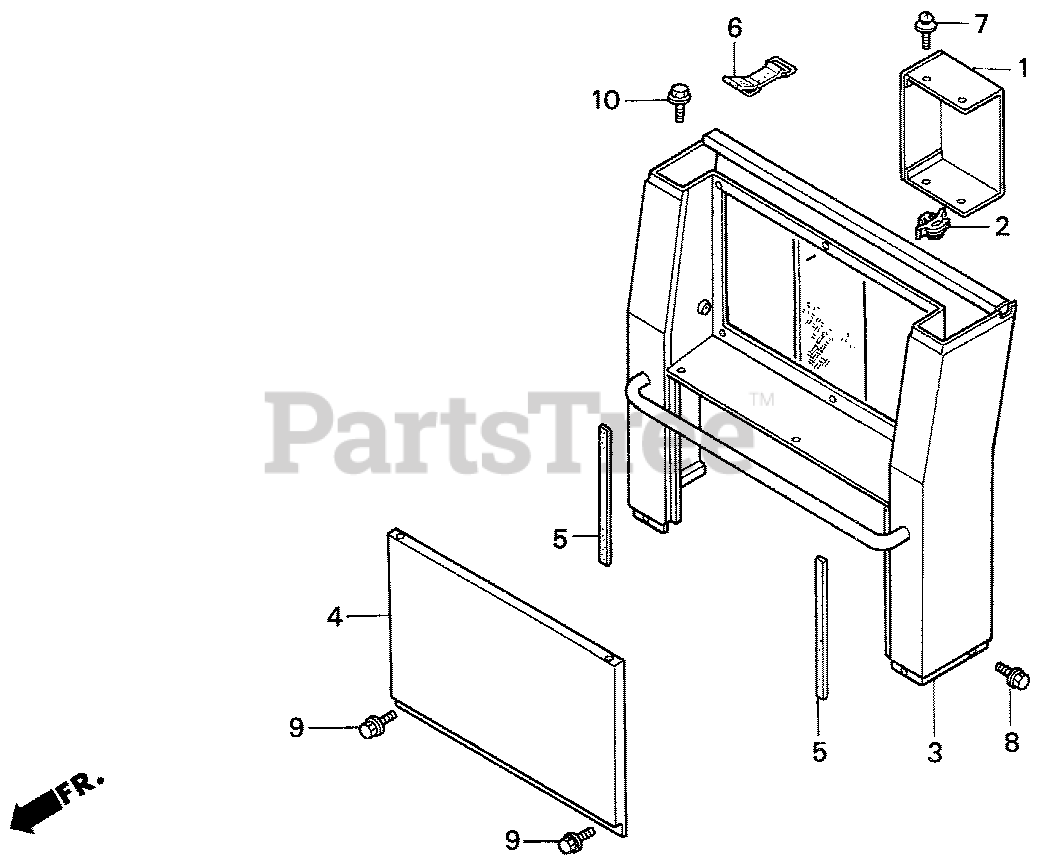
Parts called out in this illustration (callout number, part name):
1	COVER, CONTROL
2	CLIP, WIRE HARNESS
3	COVER, FR. *NH213M* (MILD SILVER METALLIC)
4	COVER, ALTERNATOR MAINTENANCE *B132* (JOHN BLUE)
5	SEAL, ALTERNATOR MAINTENANCE COVER
5	SEAL, ALTERNATOR MAINTENANCE COVER Use from Frame SN 1001725.
6	BAND, TOOL SETTING
7	SCREW-WASHER (6X12)
8	BOLT, FLANGE (8X16)
9	BOLT, FLANGE (8X16) Use from Frame SN 1001725.
10	BOLT, FLANGE (6X12)
10	BOLT, FLANGE (6X12) Use from Frame SN 1001725.
